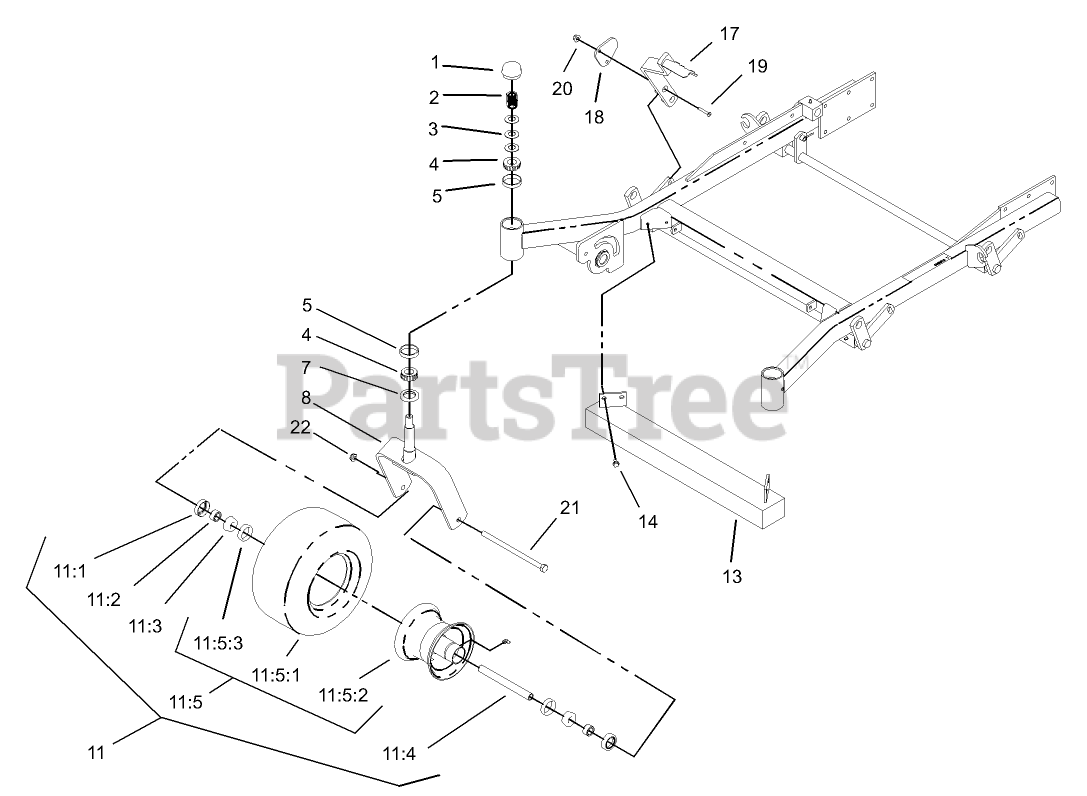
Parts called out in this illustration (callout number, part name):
1	CAP-GREASE
2	NUT-LOCK, NI
3	WASHER-BELLVILLE
4	BEARING-CONE, TAPERED
5	BEARING-CUP, TAPERED
7	SEAL-GREASE
8	CASTER-FORK
11	CASTER WHEEL ASM
11:1	SEAL-BEARING
11:2	SPACER-BEARING
11:3	BEARING-CONE, TAPER
11:4	SPACER-CASTER, FRONT
11:5	WHEEL AND TIRE ASM
11:5:3	BEARING-CUP
13	Weight ASM
14	SCREW-HWHTF
17	LEVER-LIFT, DECK
19	SCREW
20	NUT-HF
21	Screw-HH
22	NUT-LOCK, NI
